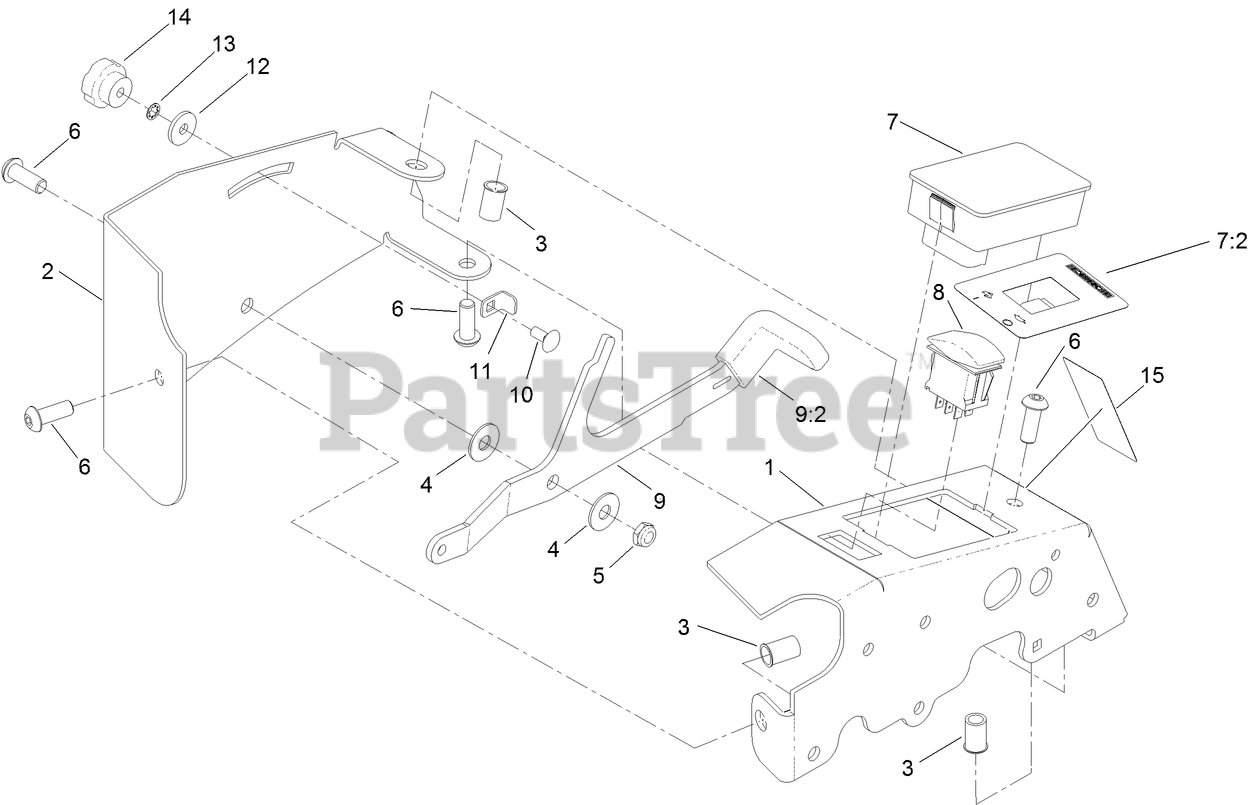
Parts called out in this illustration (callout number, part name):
1	BRACKET-MOUNT
2	COVER-CONTROLLER, SPREADER
3	NUT-CLINCH
4	WASHER
6	SCREW-HSBH
7	SPREADER CONTROL MODULE ASM
7:2	DECAL-SPEED, IMPELLER
8	SWITCH
9	HANDLE
9:2	GRIP-CONTROL, LEVER
10	SCREW-CARR
11	BRACKET-GATE, SET
12	WASHER-FRICTION
13	WASHER-LOCK, INT
14	KNOB-CHUTE
15	DECAL-CONTROL, SPREAD
